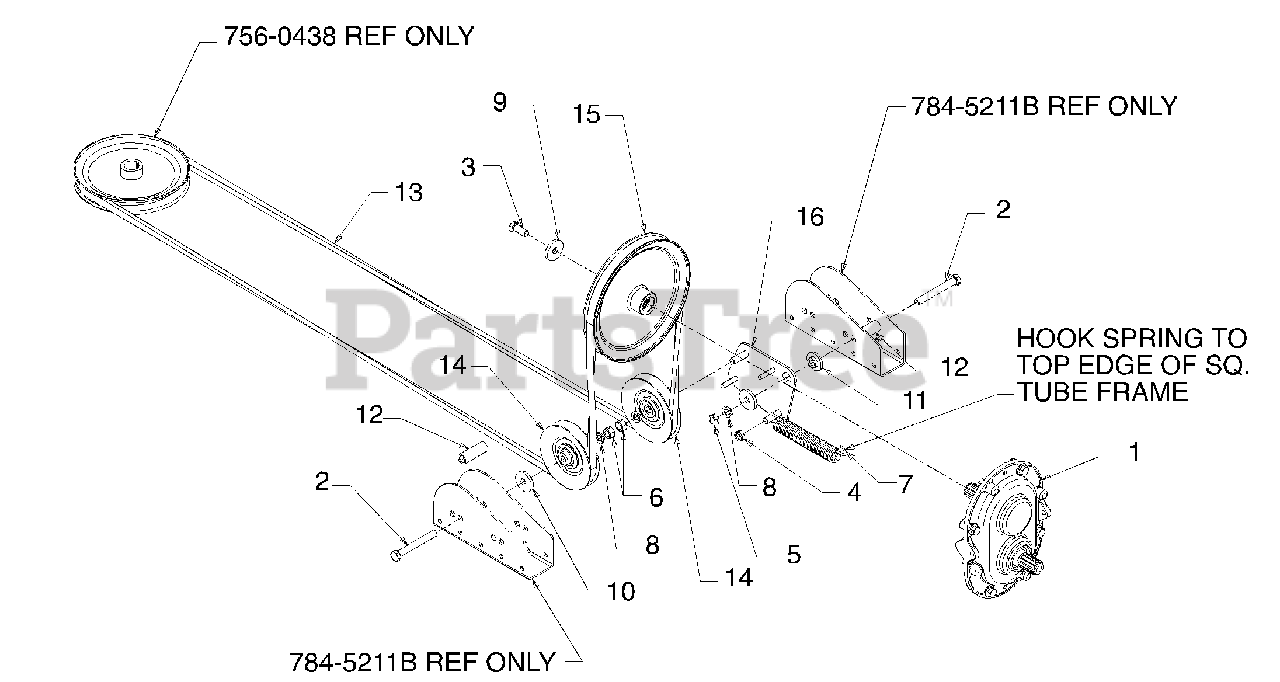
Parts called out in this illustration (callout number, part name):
1	BOX ASM:SPKT
2	HHCS:3/8-16:3.00:GR8:STD
3	HHCS:3/8-24:.875:GR8:STD
4	NUT:JAM:3/8-24:INS LOCK
5	HEX CENT L-JAM NUT 3/8-16
6	NUT:3/8-16:GRB:HX
7	SPR:EXTN:.87 DIA X 6.00 LG
8	WASH:LOCK:3/8:REGULAR DUTY
9	FL-WASH .406 ID X 1.25 OD
10	FLAT WASHER .406 ID X 1 1/4 OD
11	SHLD SPACER .625 ID X .169
12	SPACER .32 ID X .625 OD X 1.74
13	BELT:V TYP:A SECT X 113" POLY
14	V-BELT IDLER-.38 ID X 4.0 DIA
15	PUL:DR:7.00 DIA
